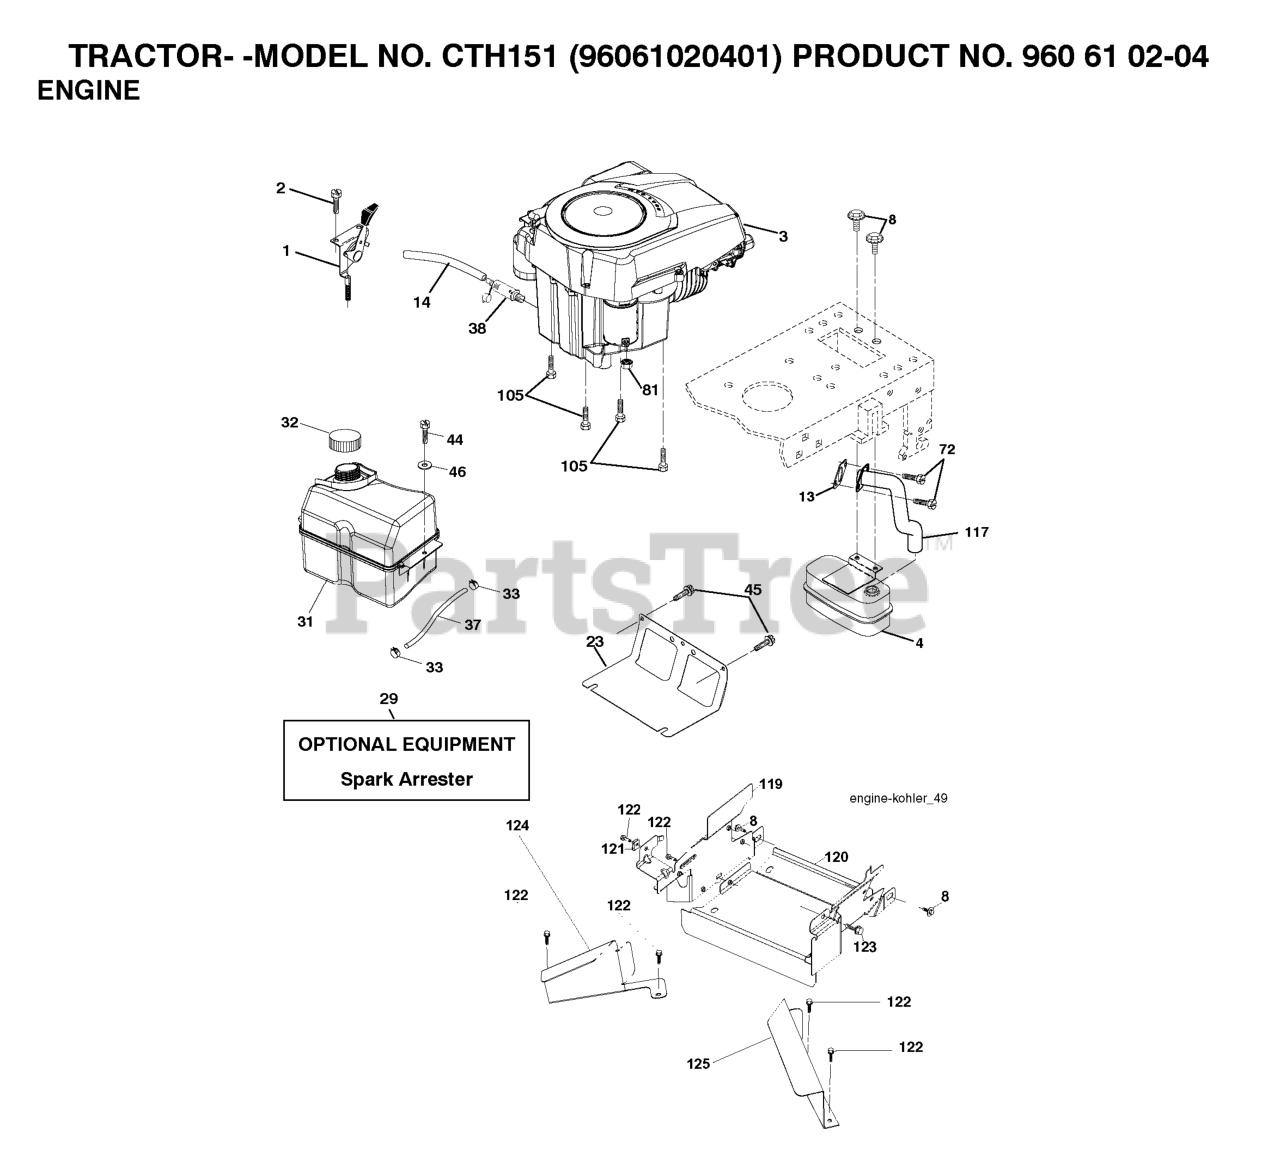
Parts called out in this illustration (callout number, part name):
1	CONTROL.TH/CK.C.
2	SCREW
4	MUFFLER.SINGLE.CYL.KOHL/B&S
8	BOLT.5/16-18UNCX3/4 W/SEMS.BLK
13	GASKET.EXHAUST.KOHLER
14	TUBE, DRAIN OIL ASM.
23	SHIELD.BROWNING.DBR.GUARD
29	KIT.SPARK ARRESTOR 794945 B&S
31	RP TANK FUEL FRT 1.5 GAL
32	FUEL CAP
33	HOSE CLAMP
37	LINE.FUEL.20
38	PLUG DRAIN OIL EASY
44	SCREW HEXWSHR 1/4-20X3/4
45	SCREW, 3/8-16X3/4
72	SCREW.SOCKET HD.5/16-1
81	NUT
105	SCREW 3/8-16X1
117	RP.TUBE.EXHAUST.KOHL.COURAGE
119	LENKRAD
120	GUARD 532199767
122	SCREW.1/4-20X5/8
123	SCREW, 5/16-18 X 1/2
126	SCREW
